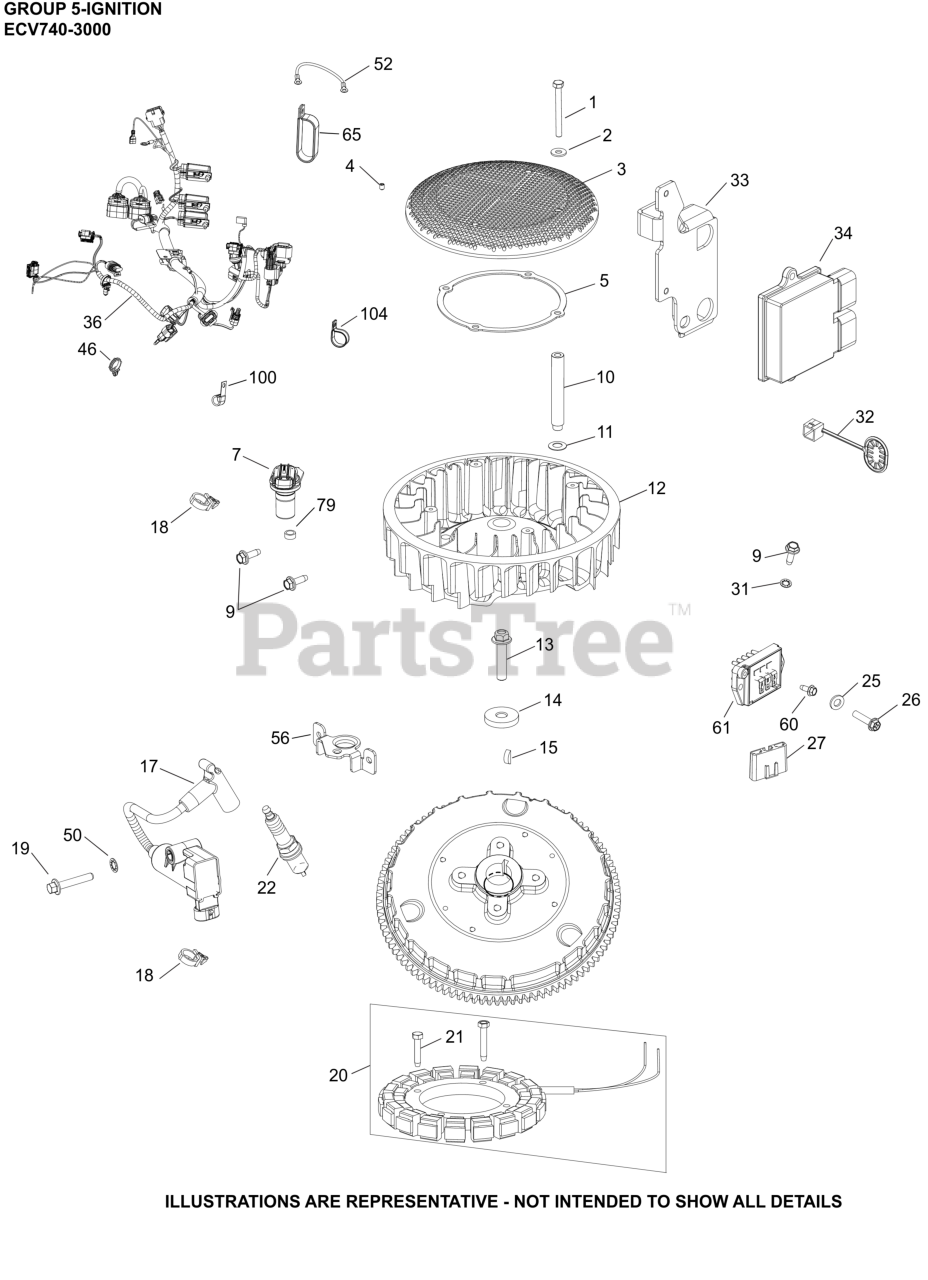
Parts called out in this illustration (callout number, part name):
1	SCREW, CAP M6X1.0X99.5
2	WASHER, FLAT 1/4" (O.D. 5/8")
3	SCREEN, GRASS
4	SCREW, SKT SET #10-24X1/4"
5	RING, SUPPORT
7	SENSOR, SPEED
9	SCREW, THREAD FORMING
11	WASHER, SPRING 10 MM
13	SCREW, HEX FLANGE
14	WASHER, FLAT
15	KEY, 3/16" X 5/8"
17	COIL, IGNITION - EFI
19	SCREW, HEX FLANGE
20	KIT, 15 / 20 AMP STATOR
21	SCREW, THREAD FORMING
22	SPARK PLUG, RFI
25	WASHER, FLAT 1/4" (O.D. 1/2")
26	SCREW, HEX FLANGE HI-LO
27	CONNECTOR
31	WASHER, INT TOOTH LOCK #10
32	CAP, CONNECTOR
33	BRACKET, ECU
34	MODULE, ECU ECV740
36	HARNESS, WIRING ASSEMBLY
46	RETAINER, WIRE HARNESS
50	WASHER, INT TOOTH LOCK 1/4"
56	BRACKET, SENSOR
60	SCREW, THREAD FORMING
61	REGULATOR, RECTIFIER (20-30AMP,FW W/OVP)
65	CLAMP, INSULATED DOUBLE
100	CLIP, CABLE (KM)
104	CLAMP, INSULATED
NI	FLYWHEEL, ASSEMBLY-USE 24 025 115-S
